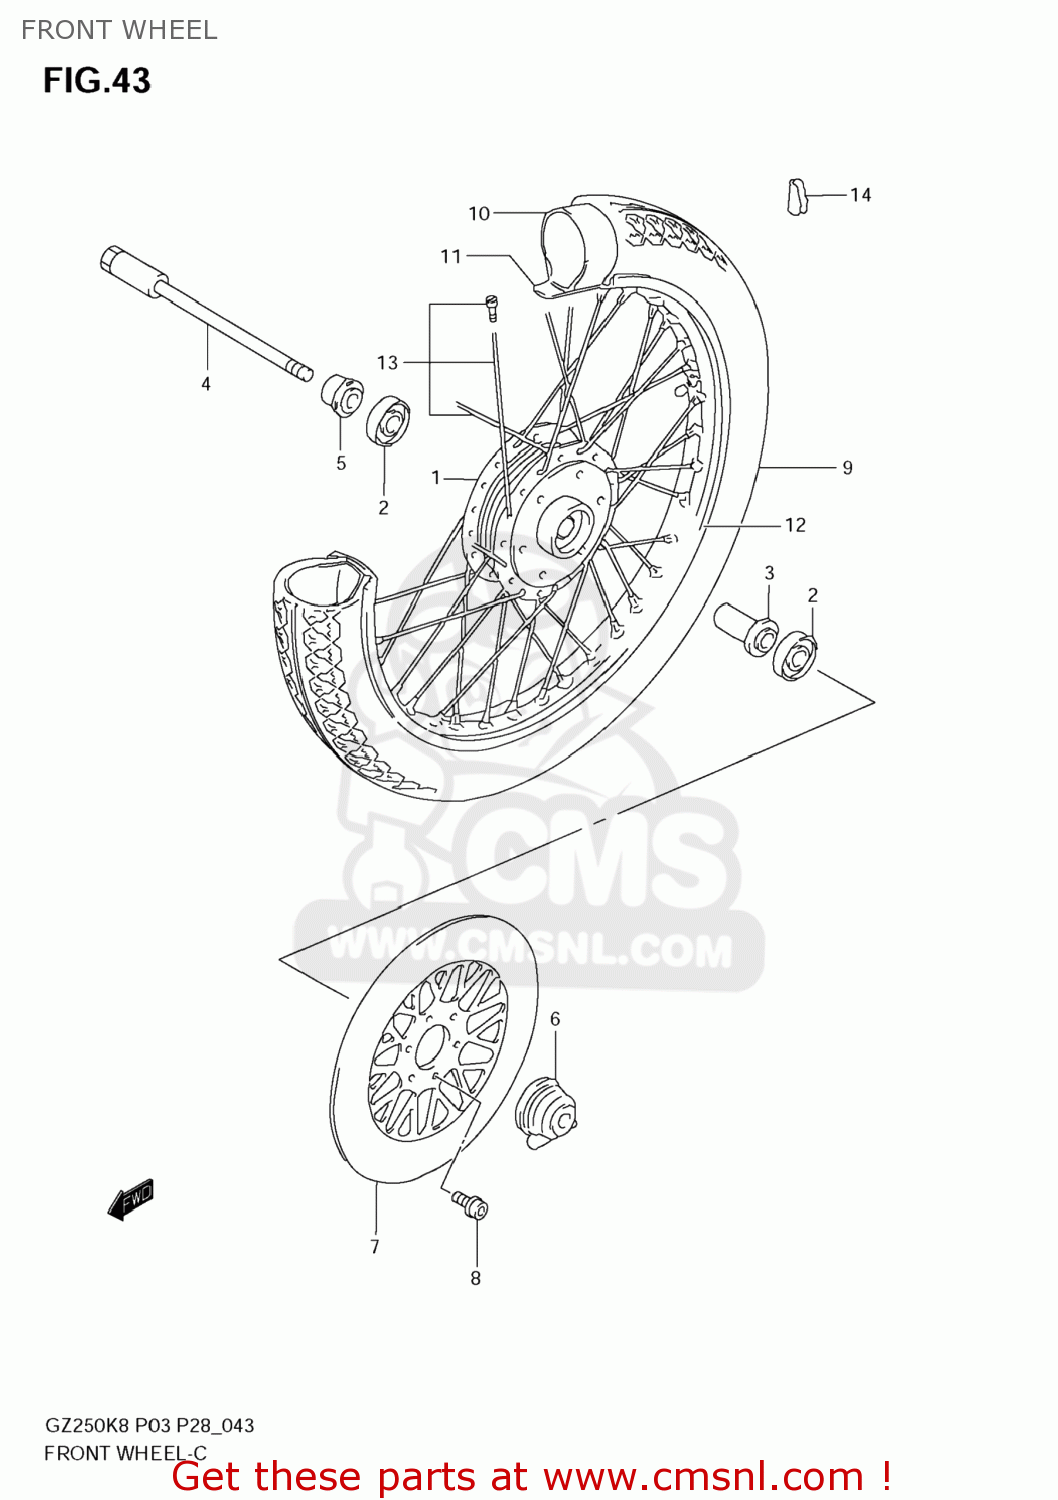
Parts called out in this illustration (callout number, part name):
1	HUB,FR WHEEL
2	BEARING
3	SPACER,FR HUB BEARING
4	AXLE FRONT
5	SPACER,FR HUB BEARING,R
6	BOX ASSY,SPEEDOMETER GEAR
7	DISC GZ125/K2-
8	BOLT(8X30)
9	TIRE, FRONT (110/90-16)
10	TUBE ASSY,WHL I
11	PROTECTOR, INNER TUBE
12	RIM,FR WHEEL(16XMT2.50)
13	SPOKE SET,FR WHEEL
14	BALANCER,WHEEL(15G)
